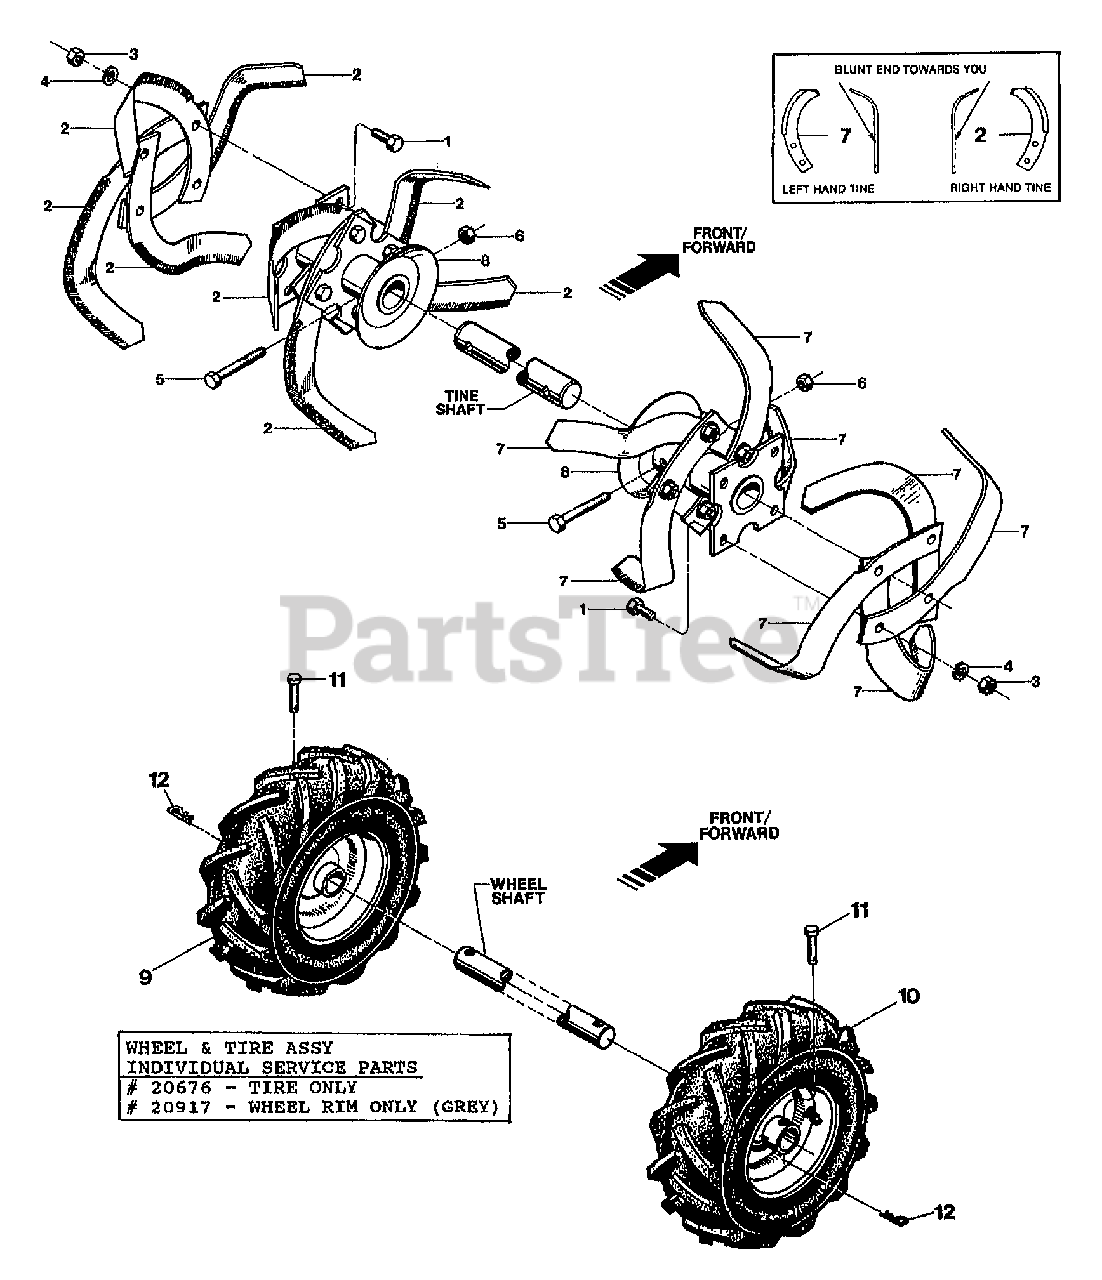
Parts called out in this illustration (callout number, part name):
1	SCR-HH 3/8-16X1.0 G5 ZP
2	TINE-BOLO RT W/HDW
3	NUT-HEX 3/8-16 ZP
4	WASHER-LK .375 @ DEPL
5	SCR-HH 3/8-16X2.00 G8
6	NUT-H/LK 3/8-16
7	TINE-BOLO LT W/HDW
8	WELD-TINE HOLDER PONY
9	ASSM-TIRE LT 4.10 X 6" (10-20 LBS. AIR REQ'D)
10	ASSM-TIRE RT 4.10 X 6" (10-20 LBS. AIR REQ'D)
11	PIN-CLEVIS
12	PIN-CLIP .08
